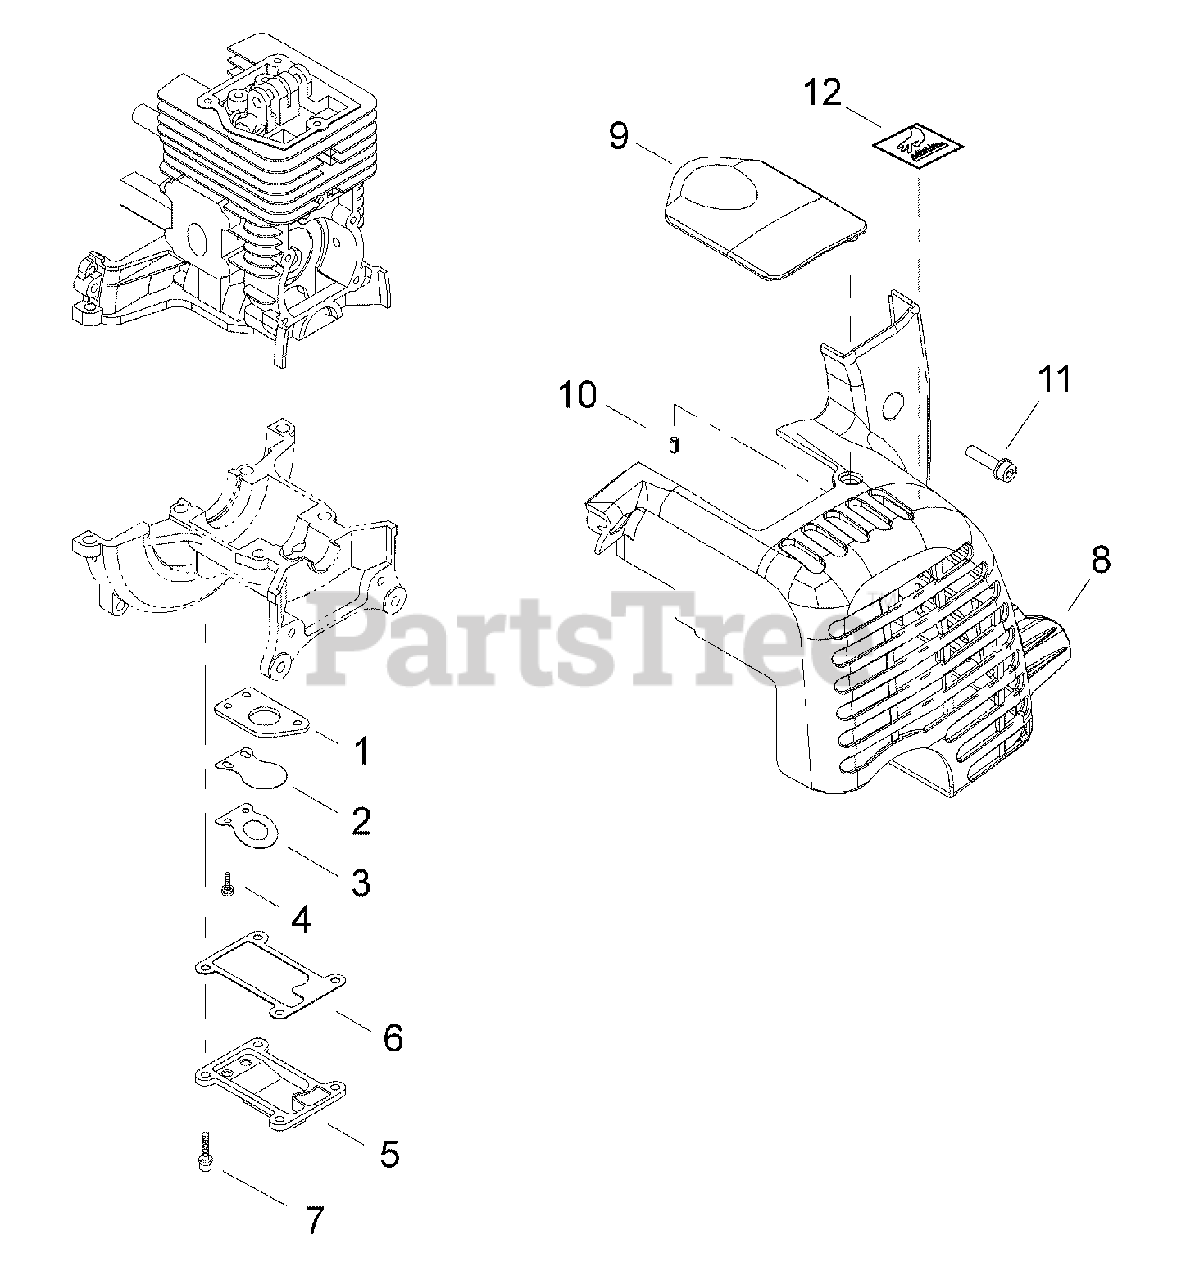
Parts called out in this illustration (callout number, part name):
1	PLATE, REED BACKING
2	VALVE, REED
3	STOP, REED VALVE
4	SCREW M3×10
5	COVER, REED VALVE
6	GASKET, REED VALVE
7	BOLT M4×14
8	COVER, ENGINE
9	COVER, SPARK PLUG
10	PIN, SPRING 4×8
11	BOLT M5×20
12	LABEL, CAUTION - HOT
